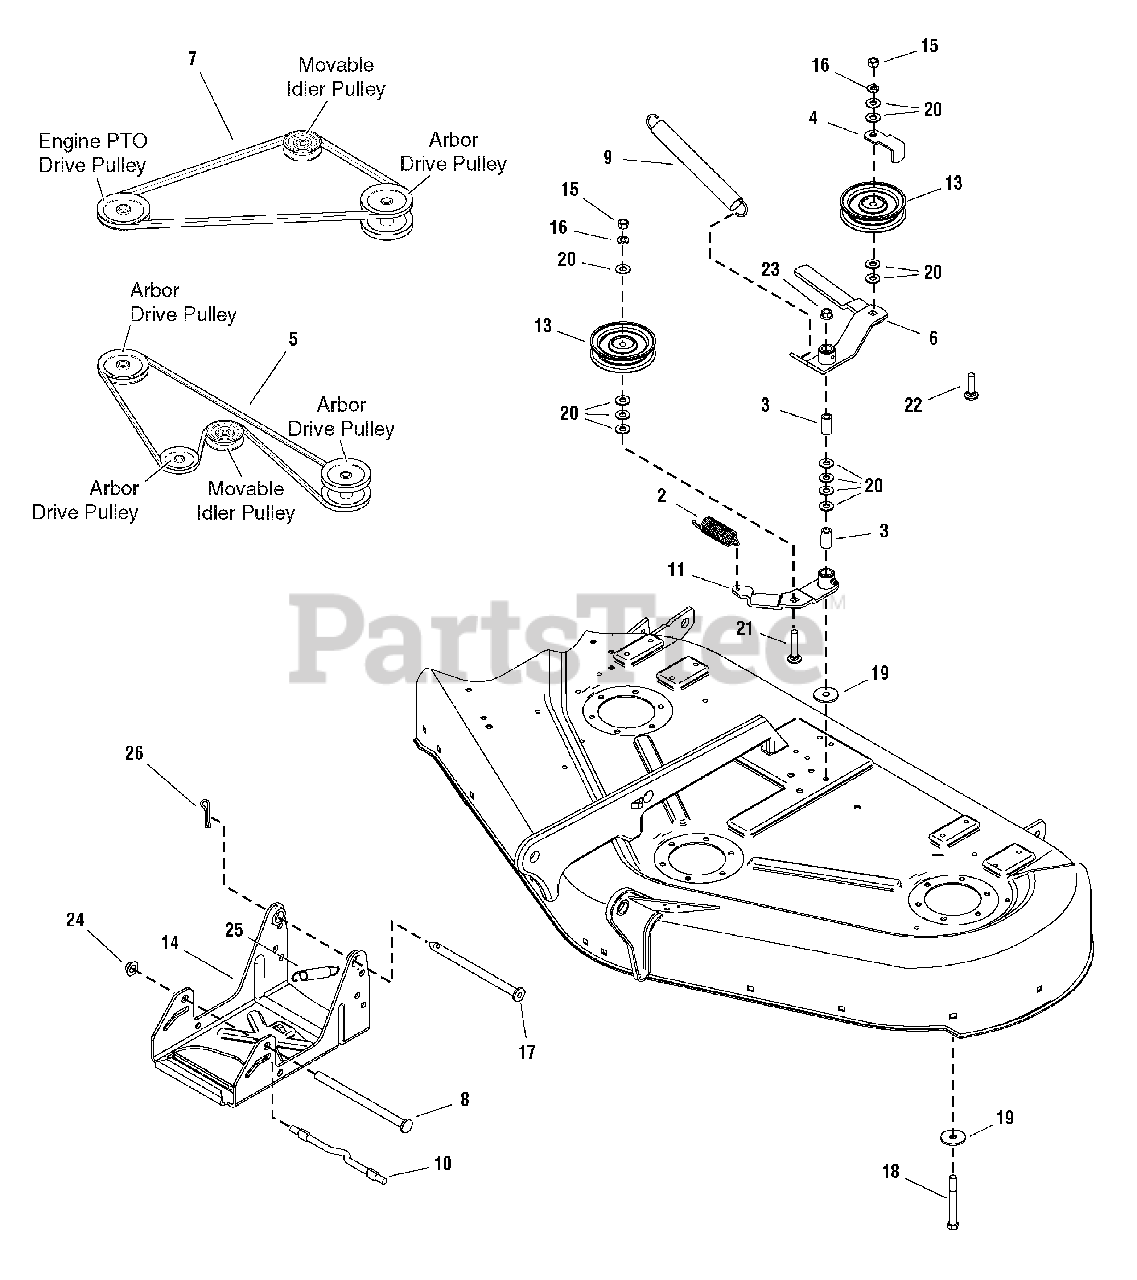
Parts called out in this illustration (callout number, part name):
2	SPRING, Extension
3	SPACER, Case Hard
4	GUARD, Belt
5	V BELT, Arbor Drive 50
6	LEVER ASSEMBLY, Idler w/Bushings & Fitting
7	V BELT, Mower Drive 50
8	ROD
9	SPRING, Extension
10	ROD
11	LEVER ASSEMBLY, Idler w/Bushings & Fitting
13	PULLEY, Idler
14	HITCH, Mower 44, 50"
15	NUT, Hex 3/8-16 NC-2B
16	LOCKWASHER, Spring 3/8
17	CAPSCREW, Hex Head 3/8-16 x 1-3/4 G8
18	CAPSCREW, Hex Head 3/8-16 x 3-1/2 G5
19	WASHER, 3/8
20	WASHER, 3/8
21	CARRIAGE BOLT, 3/8-16 x 1-1/2 G5
22	CARRIAGE BOLT, 3/8-16 x 2 G5
23	NUT, Hex Flange 3/8-16 Machine Lock
24	NUT, Push
25	SPRING
26	PIN, Klik, 3/16 x 1-5/8
